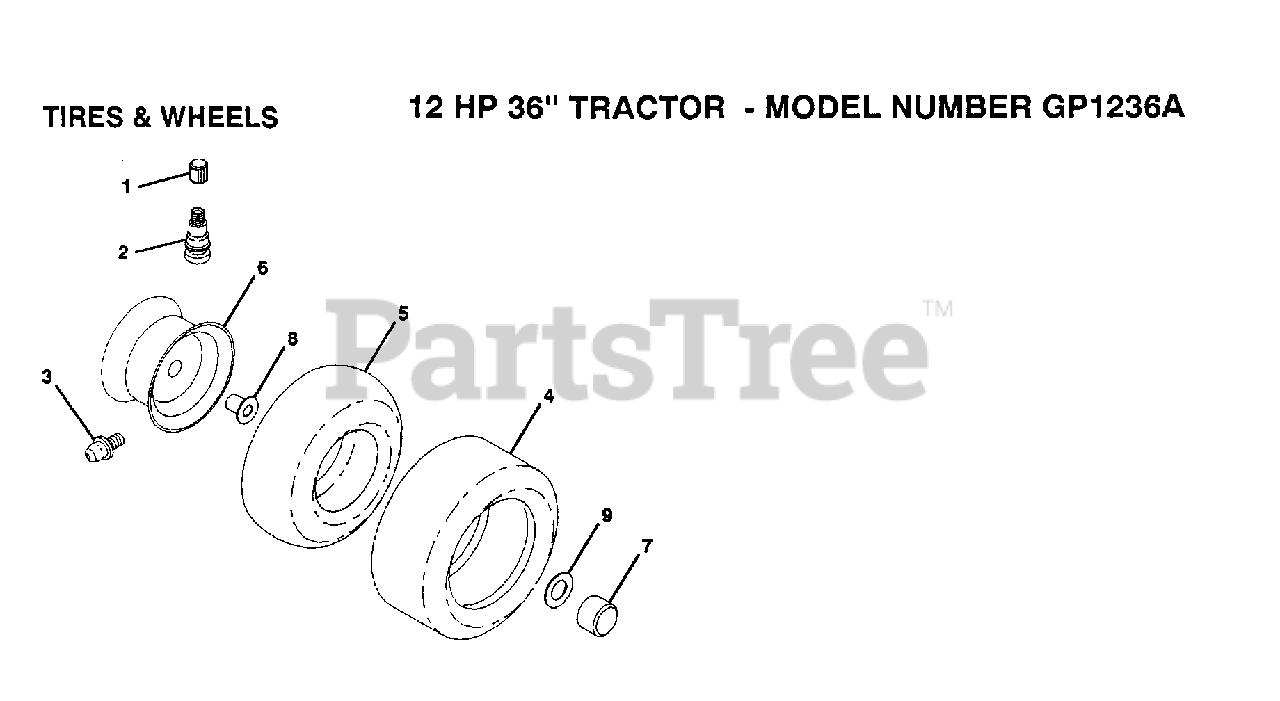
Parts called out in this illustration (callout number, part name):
1	VALVE CAP
2	VALVE STEM LT
3	FITTING LT
4	TIRE
5	TUBE.5.3/4.5/6
7	HUB CAP
8	"FLANGE, BEARING"
9	WASHER
